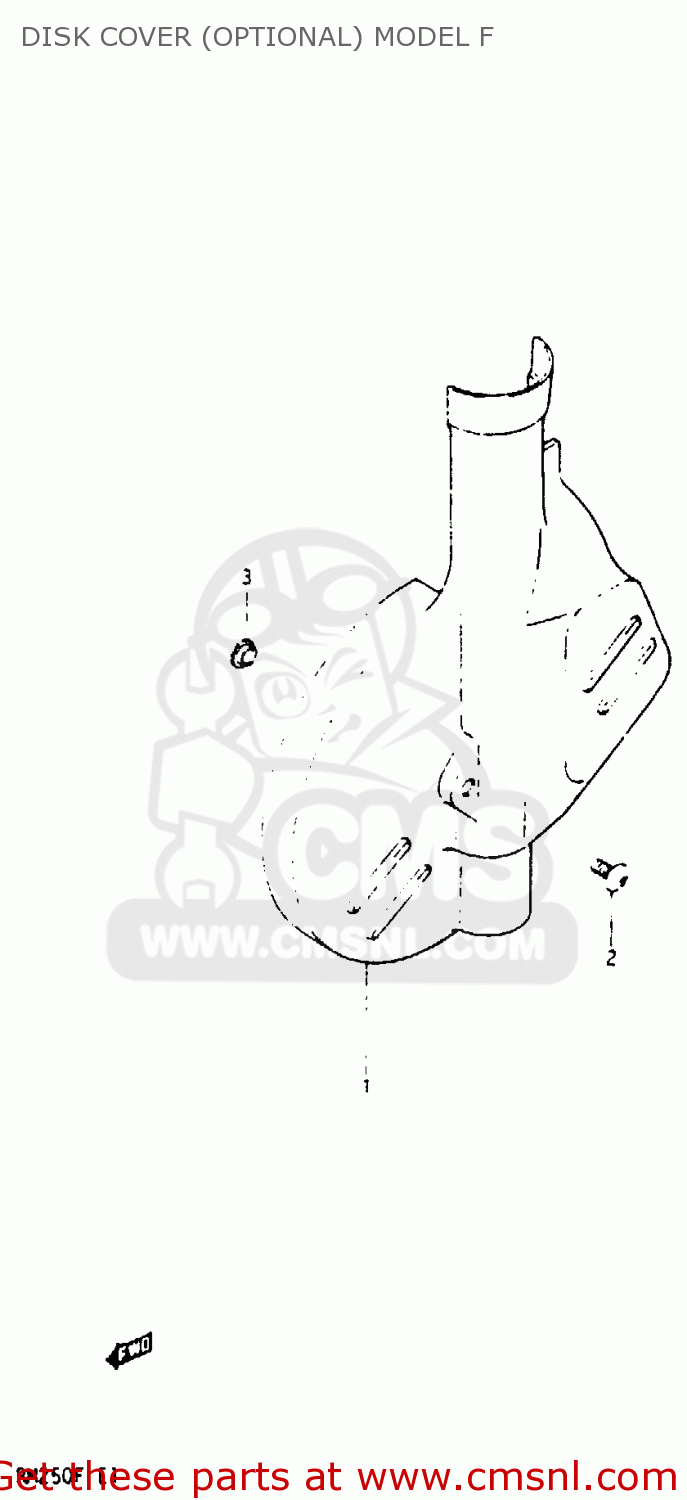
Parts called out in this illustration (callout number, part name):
1	COVER,FRONT BRAKE DISC
2	SCREW(8X12)
3	WASHER
